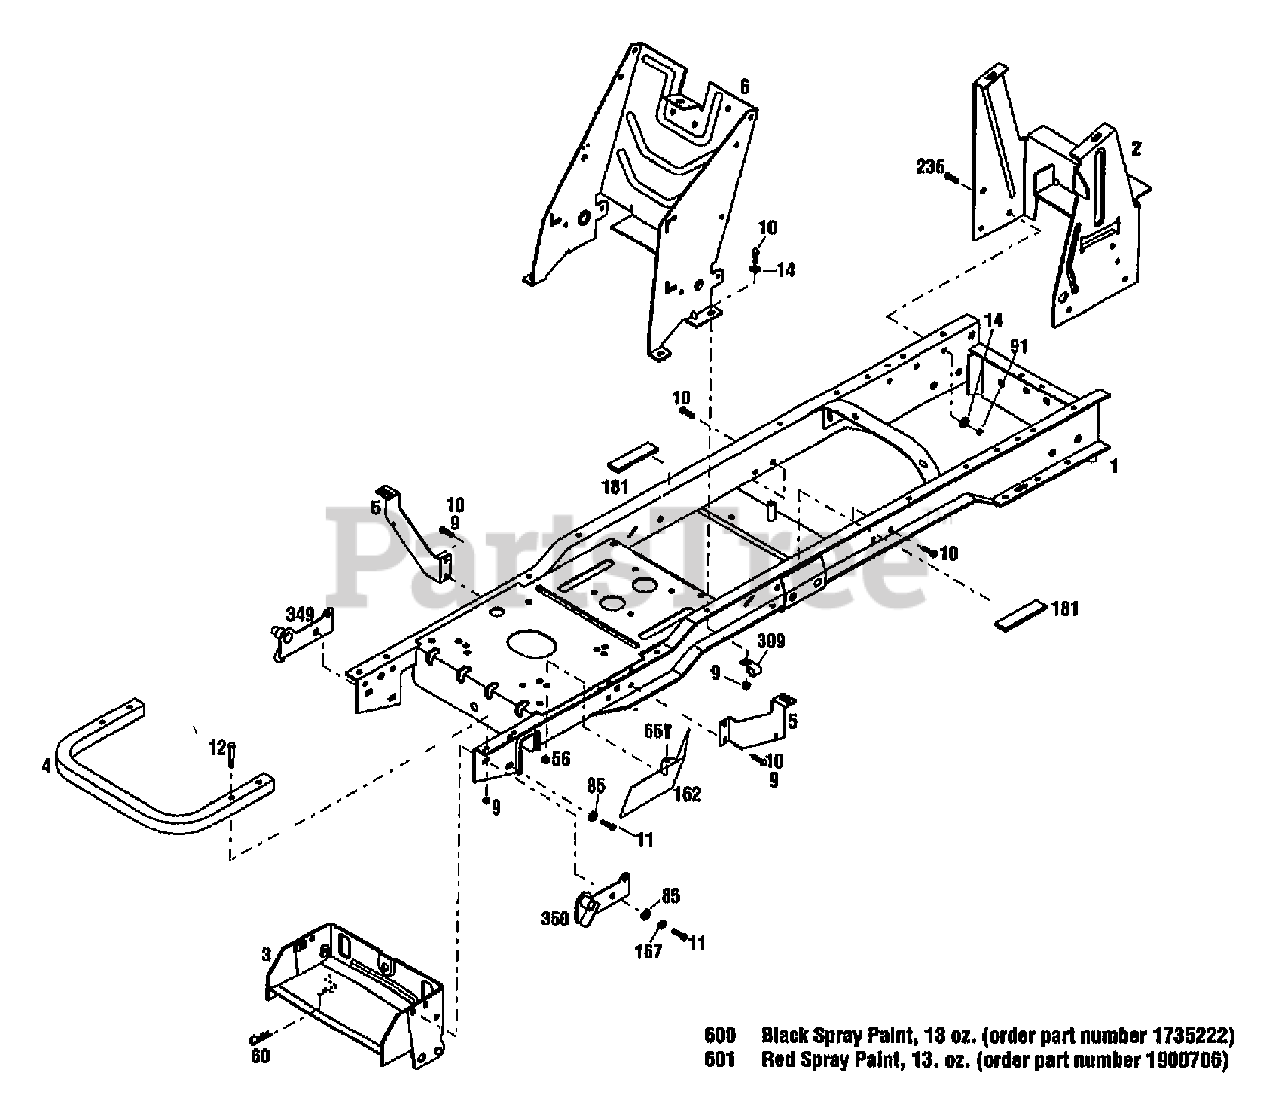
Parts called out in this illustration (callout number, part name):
1	ASSM-FRAME LTX
2	SUPPORT-REAR TANK
3	ASSM-BRKT ATTACHMENT
5	SUPPORT-FENDER
6	SUPPORT-CONSOLE
9	NUT-HFLK 5/16-18 ZP
10	SCR-HHC 5/16-18X.75 GR 5 ZP
11	SCR-HH 3/8-16X1.0 G5 ZP
12	SCR-HH 5/16-18X1.75
14	WASHER-FLAT 5/16 SAE
56	NUT-HF/LK 1/4-20 ZP
60	PIN-HITCH .125X2.56 ZP
65	SCR-HH 1/4-20X.625
85	WASHER-FLAT 3/8 SAE
91	NUT-TOP/LK 5/16-18 ZP
162	SHIELD-HEAT UPPER
167	WASHER-LK .375 @ DEPL
236	SCR-HFLK 5/16-18X.75 ZP
309	CLIP-J
349	PLATE-PIVOT RH
